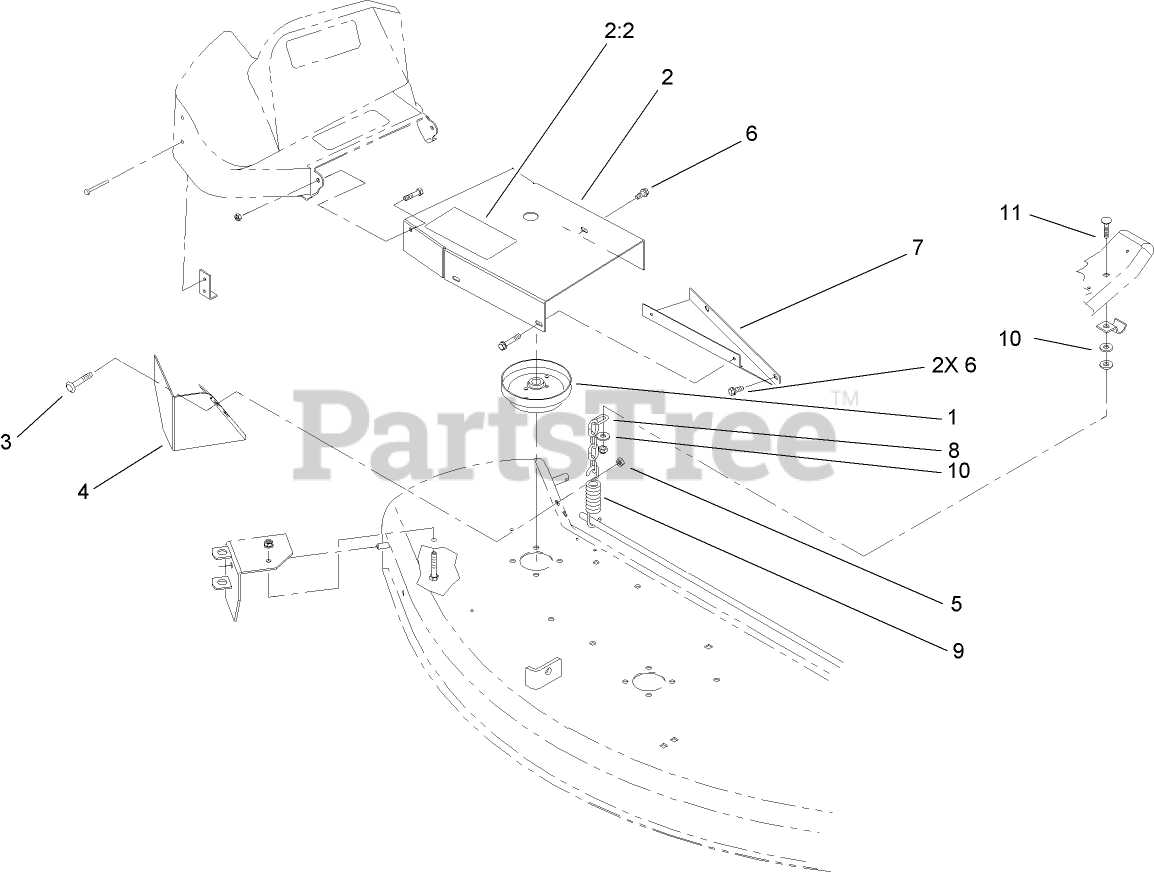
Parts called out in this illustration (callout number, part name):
1	PULLEY
2	SHIELD / DECAL ASM
2:2	DECAL-DANGER
3	SCREW-CARR
4	DEFLECTOR-GRASS
5	NUT-LOCK, NI
6	SCREW-HHF
7	ADAPTER-SHIELD
8	CHAIN
9	SPRING-EXTENSION
10	WASHER-FLAT
11	SCREW-CARR
